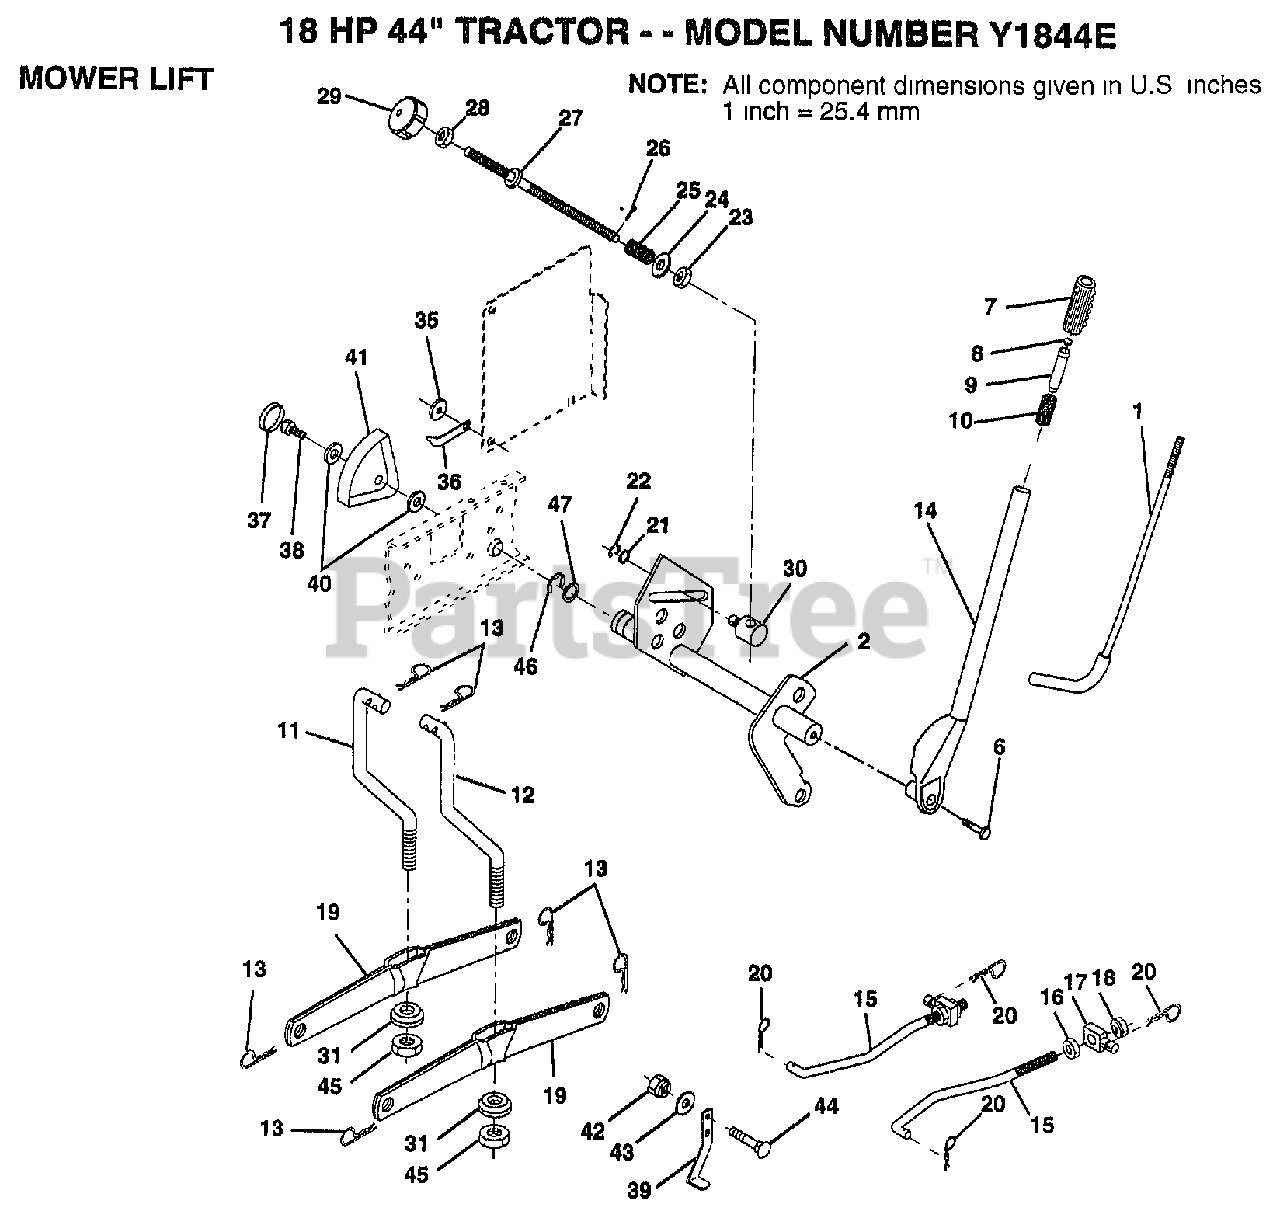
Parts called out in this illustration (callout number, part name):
1	LEVER ROD LT
2	SHAFT LIFT W/IND
6	"BOLT,HEX"
7	GRIP
10	SPRING T
11	LINK.LIFT.LH.GTV
12	LINK.LIFT.RH.GTV.
15	LINK.FRONT
16	NUT
17	TRUNION
18	NUT.LK.W/WSH.1/2.
19	ARM SUSP REAR
20	RETAINER.SPRING
21	WASHER
22	KLIP RING
23	NUT T
24	WASHER
25	SPRING T
27	ROD LIFT LT
28	NUT
29	KNOB INF 3/8-16
30	TRUNION LT
31	BEARING PVT LH
35	WASHER T
36	POINTER HGT IND
37	"PLUG,HOLE"
38	SCREW
39	STOP.OVER.CENTER
40	WASHER
41	HEIGHT INDICATOR
43	WASHER GT
44	BOLT
45	NUT.CROWNLOCK.3/8
46	E-RING
47	WASHER
